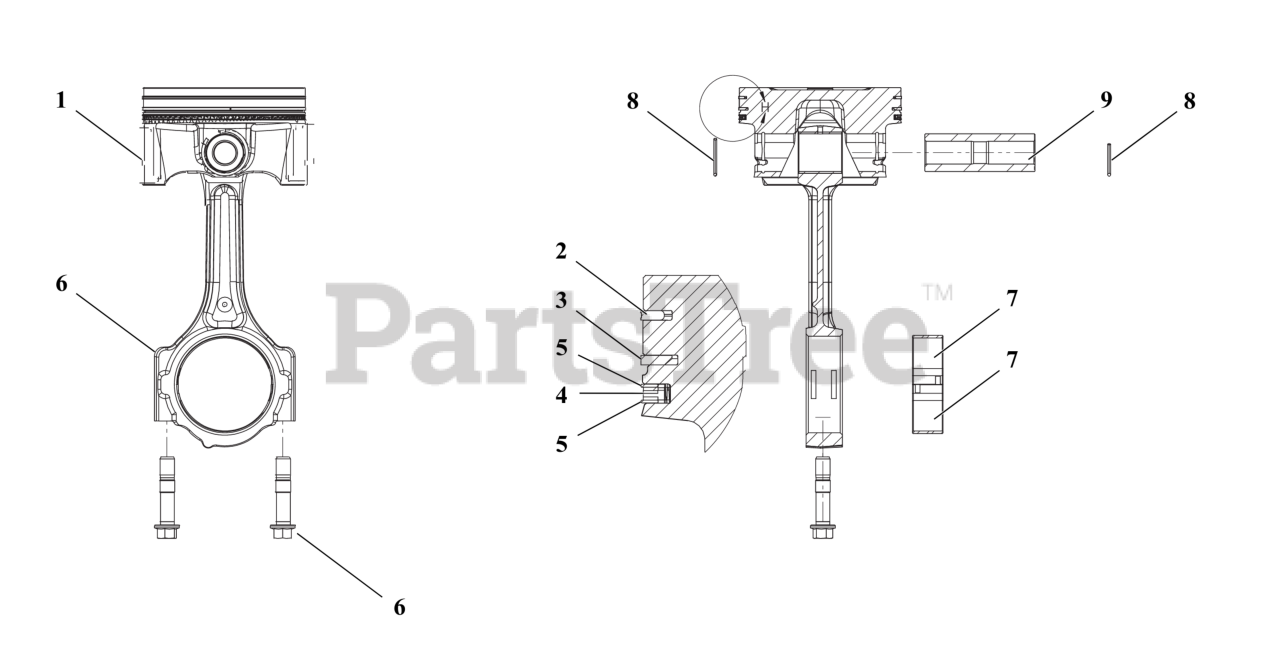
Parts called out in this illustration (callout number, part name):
1	*PISTON
2	*SET, PISTON RING
3	*SET, PISTON RING
4	*SET, PISTON RING
5	*SET, PISTON RING
6	*ROD, CONNECTING
7	*BEARING SET, C/ROD
8	*CLIP, PISTON
9	*PIN, PISTON
